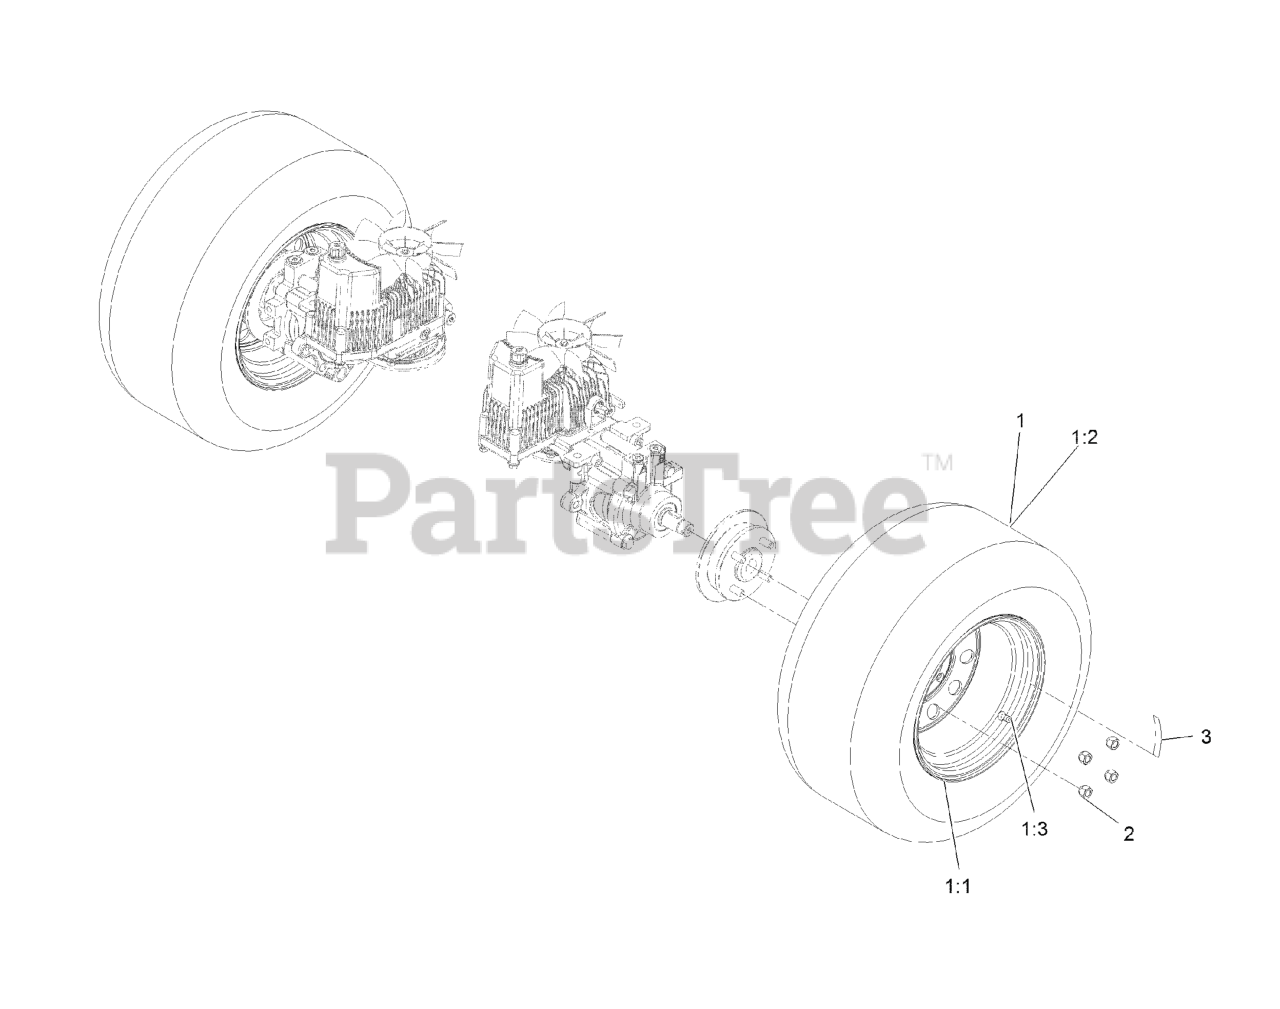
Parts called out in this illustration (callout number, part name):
1	ASM-WHEEL AND TIRE
1:1	ASM-RIM 72
1:2	TIRE-DRIVE
1:3	Stem-Valve
2	NUT-LUG
3	DECAL-TORQUE, WHEEL HUB LUG
